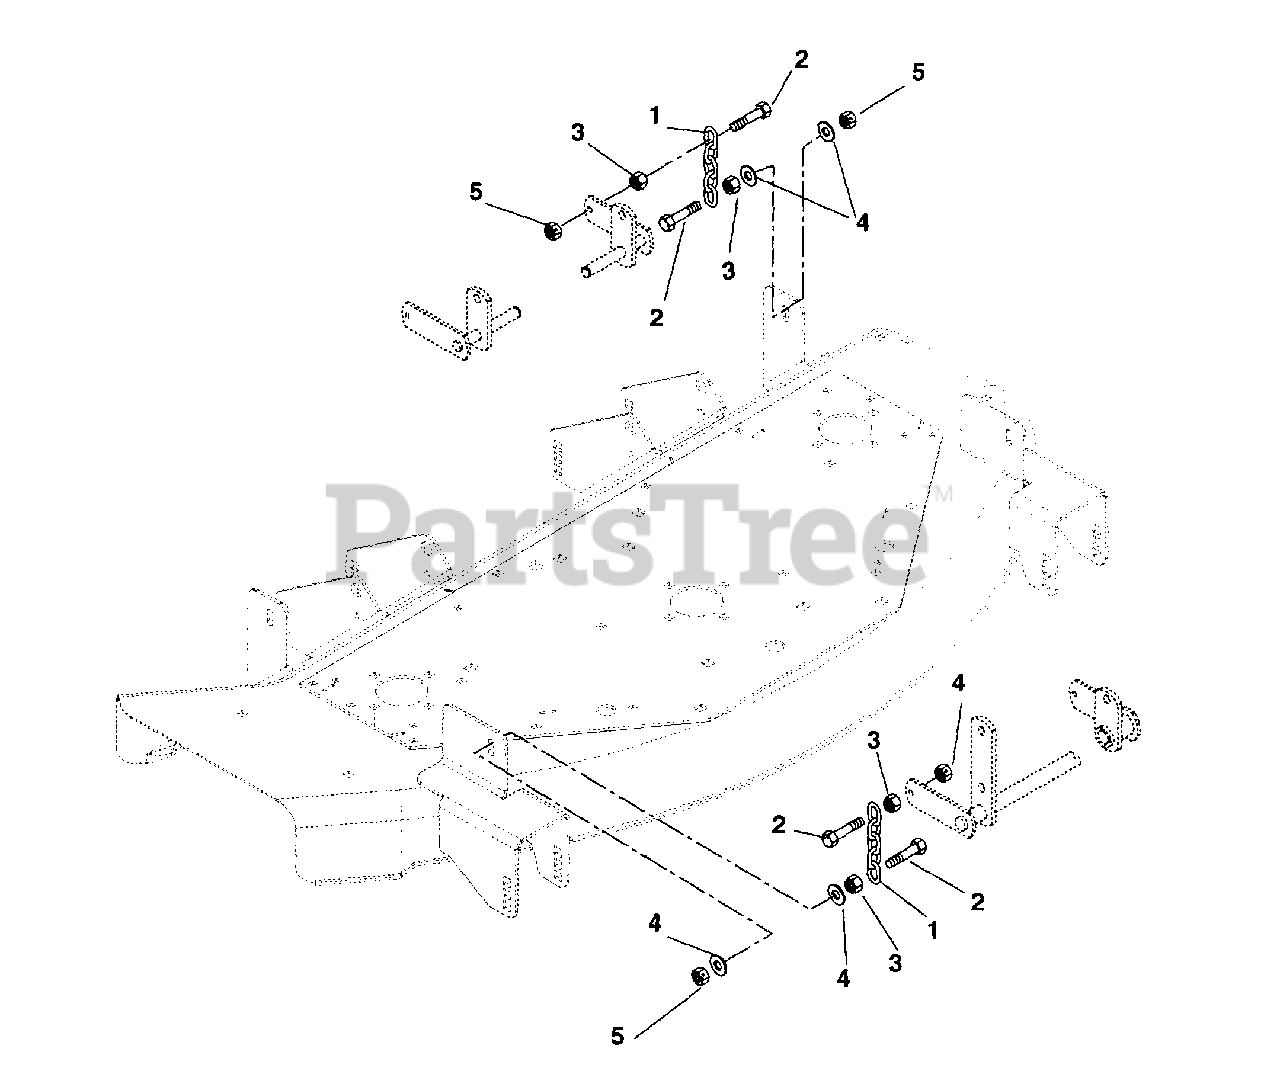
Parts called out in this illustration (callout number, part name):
1	CHAIN, LINK
2	@BLT-HEX .38-16X1.50 GR5 YWZC
3	@NUT-HEX .38-16 YWZC
4	@WSHR-FL-STL.406X.812X.065 YWZ
5	@NUT-LK-CTR .38-16 YWZC
